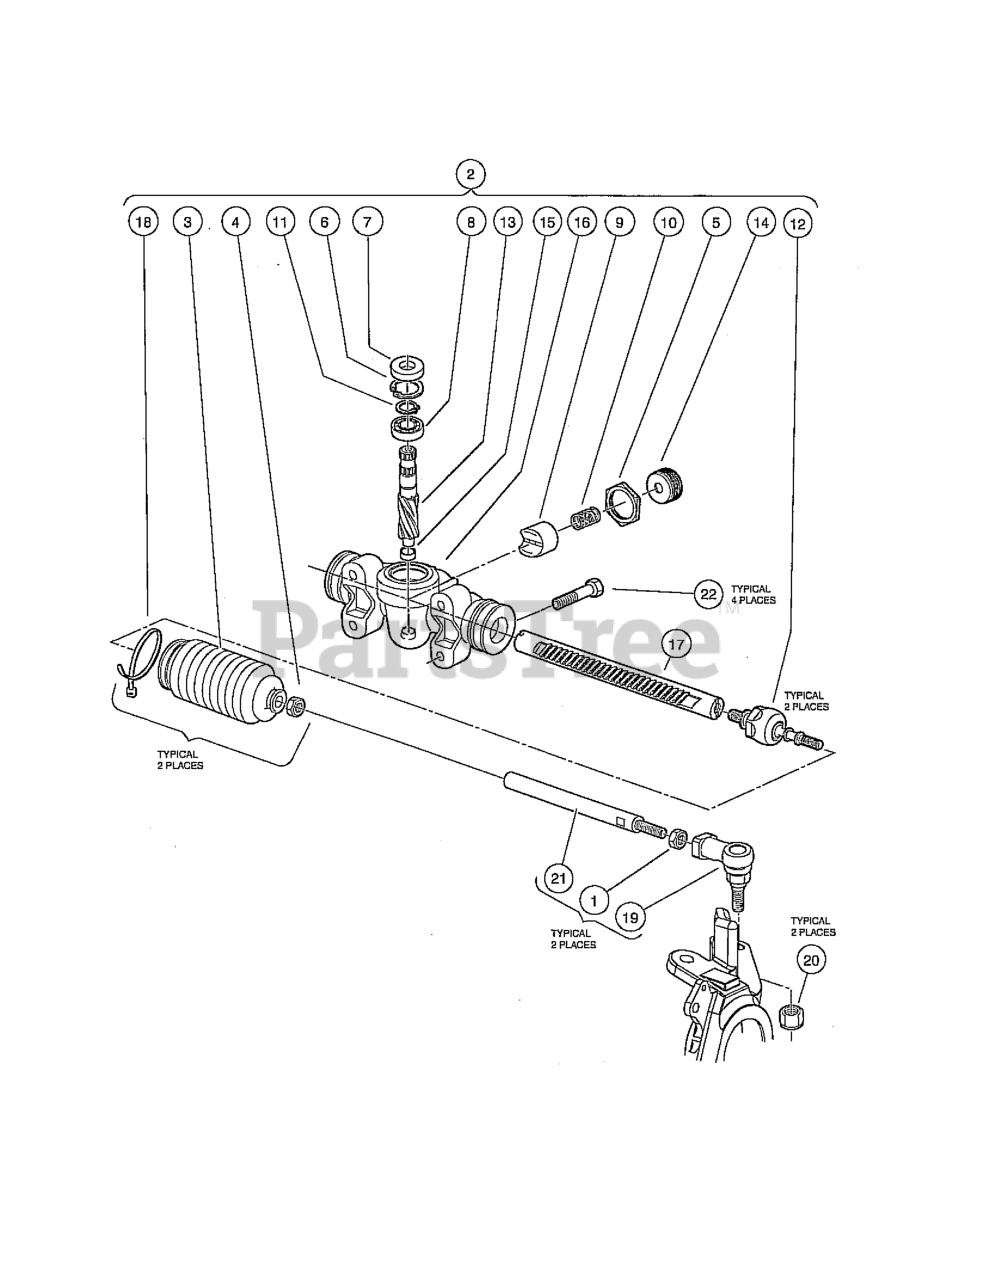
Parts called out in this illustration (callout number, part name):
1	12MM HEX NUT
2	STEERING RACK
3	BELLOWS, LONG
4	12MM HEX NUT
5	RACK SCREW LOCKNUT
7	SEAL, STEERING PINION DUST
8	BEARING BALL
9	SUPPORT YOKE
10	RACK GUIDE PRESSURE SPRING
11	C-TYPE STOP RING
12	INNER BALL JOINT ASM
18	TIE WRAP, 8" NYLON
19	TIE ROD END
20	LOCKNUT, M12-1.25 NYLON
21	LINK, DRAG
